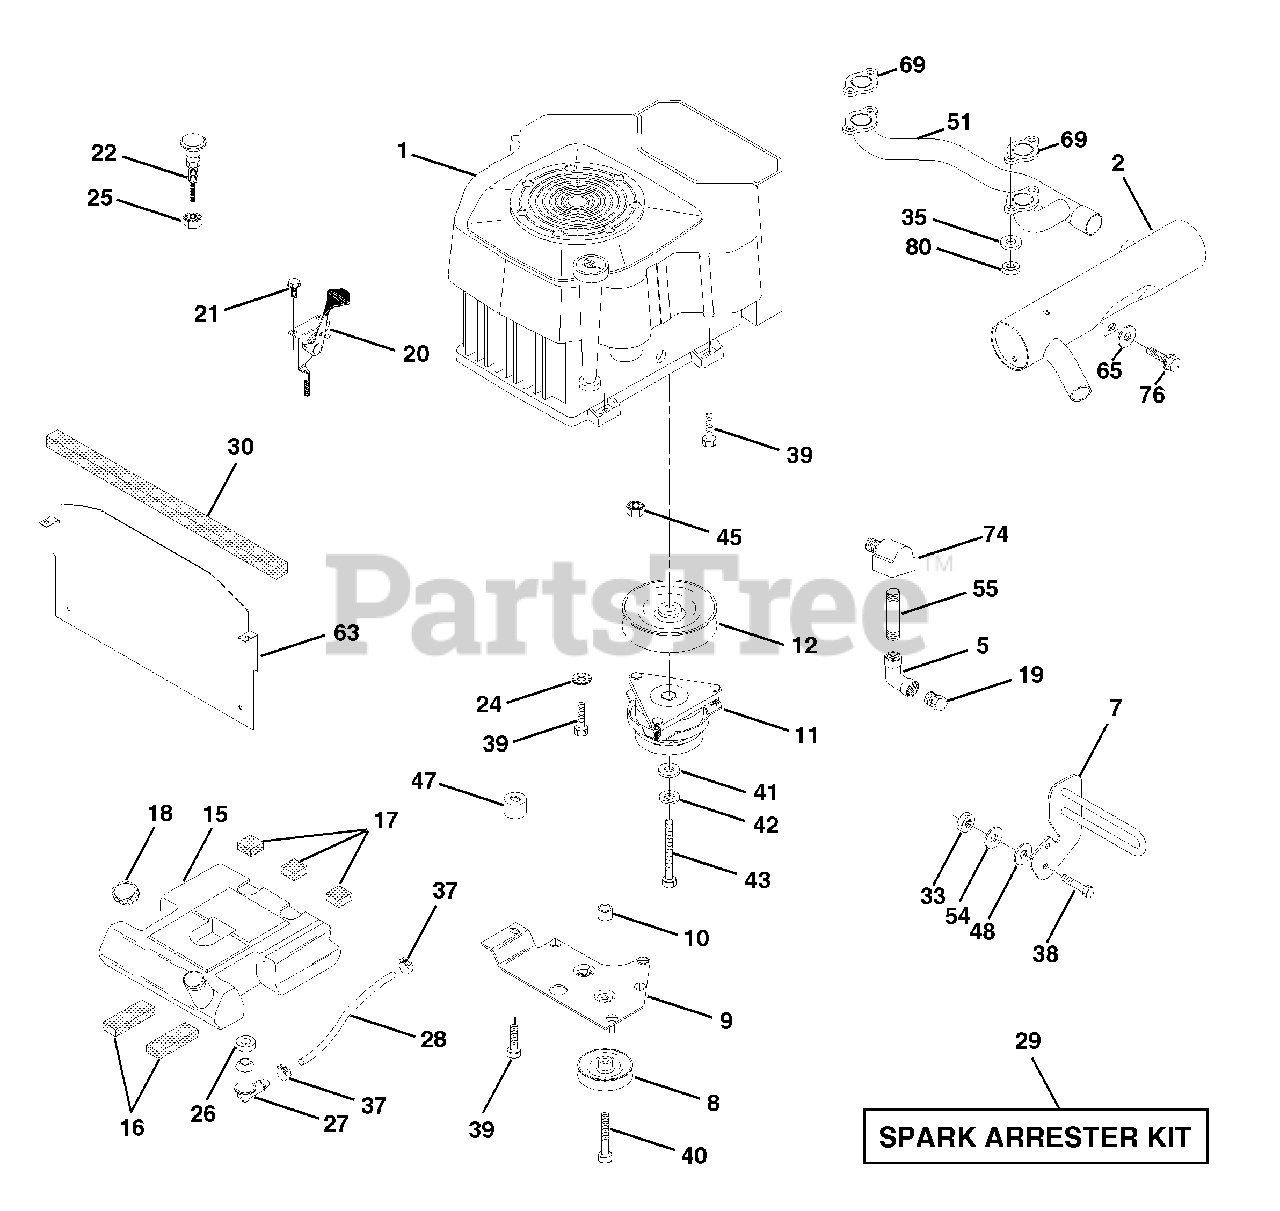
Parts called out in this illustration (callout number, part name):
2	Muffler Side 1-1/8"
5	Elbow STD 90 Degree 3/8-18 NPT
7	Muffler Assembly Guard
8	Pulley V-Idler
9	Keeper Asm Belt Engine VGT 96
11	Clutch Electric
12	Pulley Engine VGT Elect Clutch
15	Tank Fuel Rear
16	Pad Spacer
17	Pad Spacer
18	Cap Asm Fuel W/Sym Vented
19	Plug Oil Drain
20	Control Throttle
21	Screw Hex Thd Cut 1/4-20 X 5/8
22	Control Choke
24	Washer Ext Tooth 3/8
25	Nut Keps 3/8 - 24 UNF
26	Bushing
27	Stem Tank Fuel
28	Fuel Line
29	Spark Arrester Kit
30	Strip Foam 18"
33	Nut, Hex W/Ins. 3/8-16 UNC
35	Washer Split
37	Clamp Hose
38	Bolt, Fin Hex 3/8-16 UNC x 1-1/2
39	Screw TT 3/8-16 x 2-1/4 UNC
40	Screw TT 3/8-16 x 4 UNC
41	Washer 1-1/2 OD X 15/32 ID X .250
42	Washer Lock 7/16
43	Bolt Hex 7/16-20 X 4-1/4 Ga 5
45	Nut Flange 1/4-20 Starter Nut
47	Spacer Engine
48	Washer 13/32 x 1-1/4 x 7 Ga.
51	Manifold Pipe VGT CV 1-1/8
54	Washer Flat 13/32 x 7/8 x 14 Ga.
55	Nipple, Pipe 4-1/2"
63	Shield, Heat VGT YP/Husq.
65	Washer 13/32 x 1 x 14 Ga.
69	Gasket
74	Elbow Street Brass
76	Screw Thrdrol 3/8-16 x 3/4 Ty-TT
80	Nut Flange
